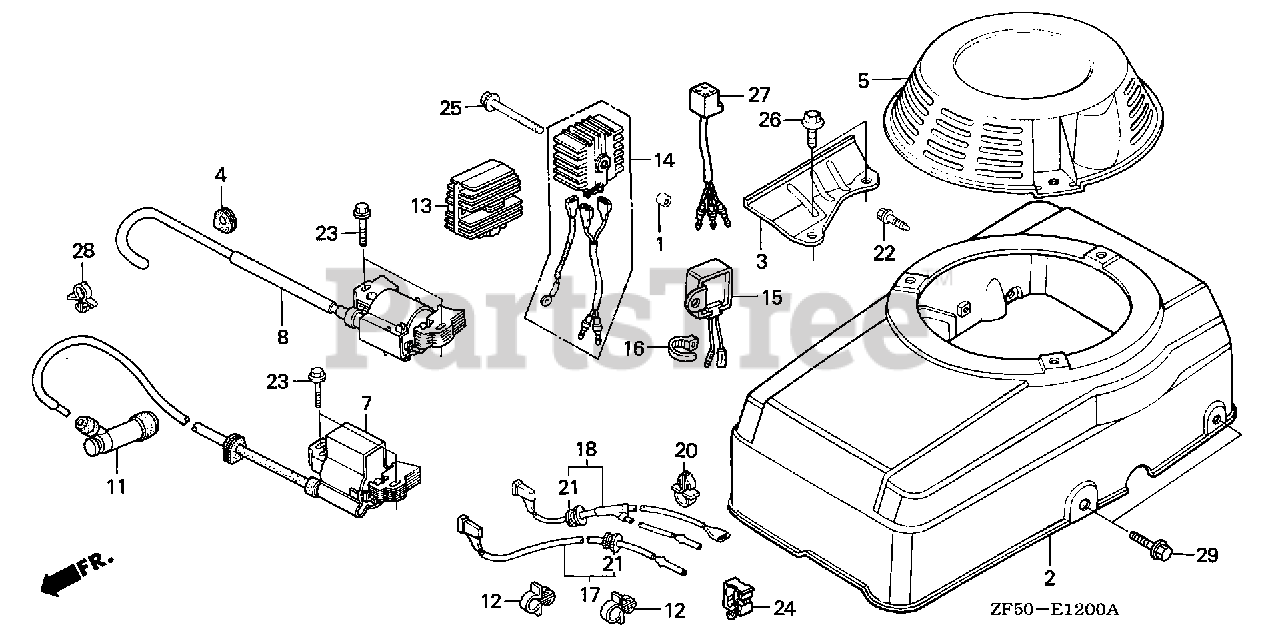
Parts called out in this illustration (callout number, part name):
2	COVER, FAN *R8* (BRIGHT RED)
3	PLATE, SIDE Use up to Engine SN 2033446.
3	PLATE, SIDE
7	COIL ASSY., IGNITION
11	CAP ASSY., NOISE SUPPRESSOR
12	CLIP, IGNITION WIRE (8MM)
18	WIRE, STOP SWITCH
21	GROMMET, WIRE CORD
22	BOLT, FLANGE (6X12) (CT200)
23	BOLT, FLANGE (6X28) (CT200)
26	BOLT, FLANGE (8X20)
